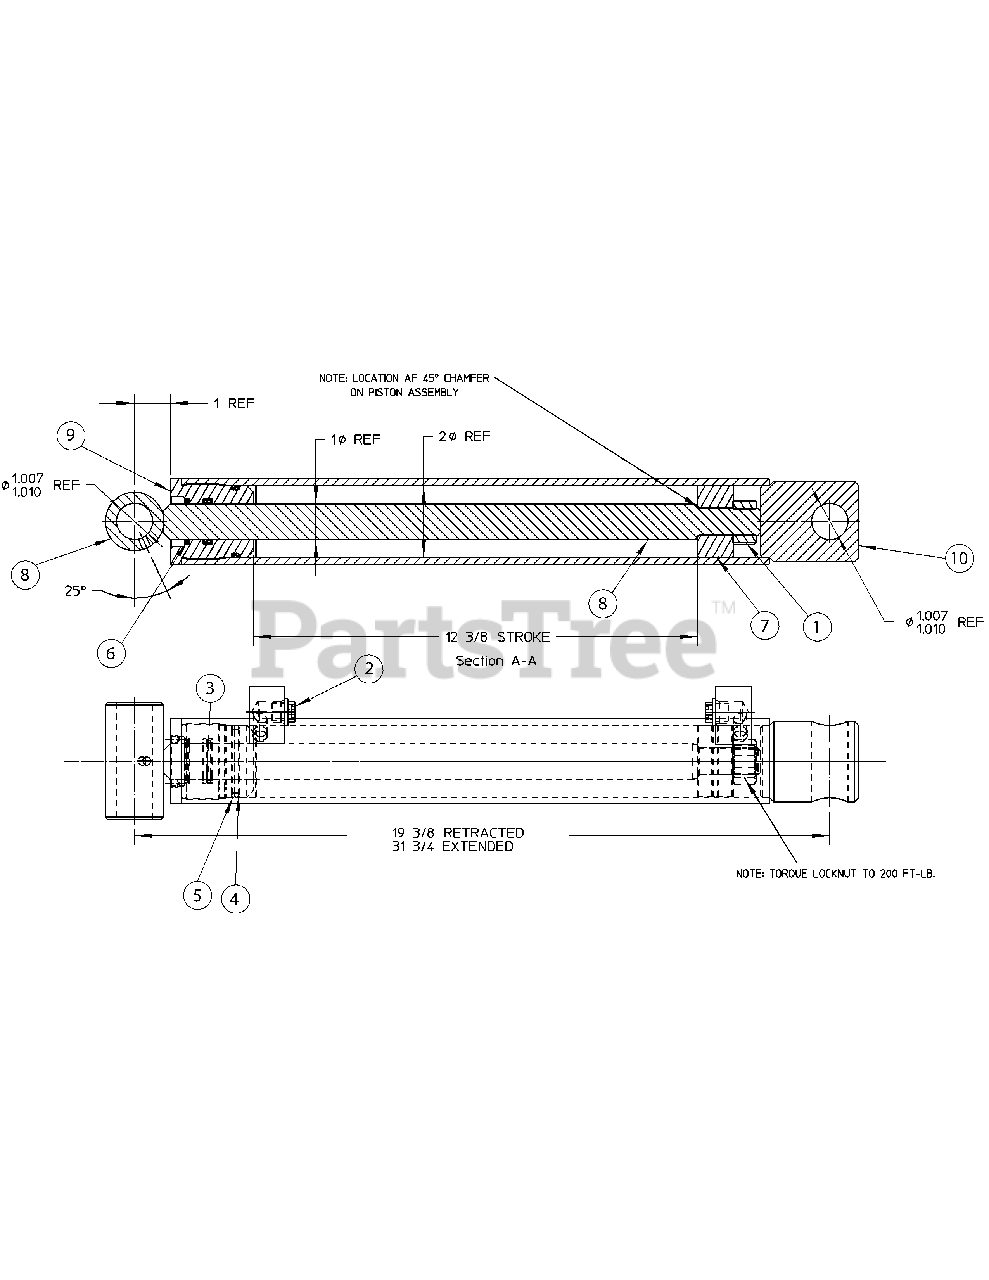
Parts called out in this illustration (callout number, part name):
1	Nut, 3/4 NF Nylok
2	Cap Plug, 9/16-18 Th’d with O-Ring
3	Rod Seal*
4	O-Ring*
5	Back-Up Ring*
6	Rod Wiper*
8	Piston Rod Weldment
9	Threaded Gland
10	Cylinder Tube Weldment
